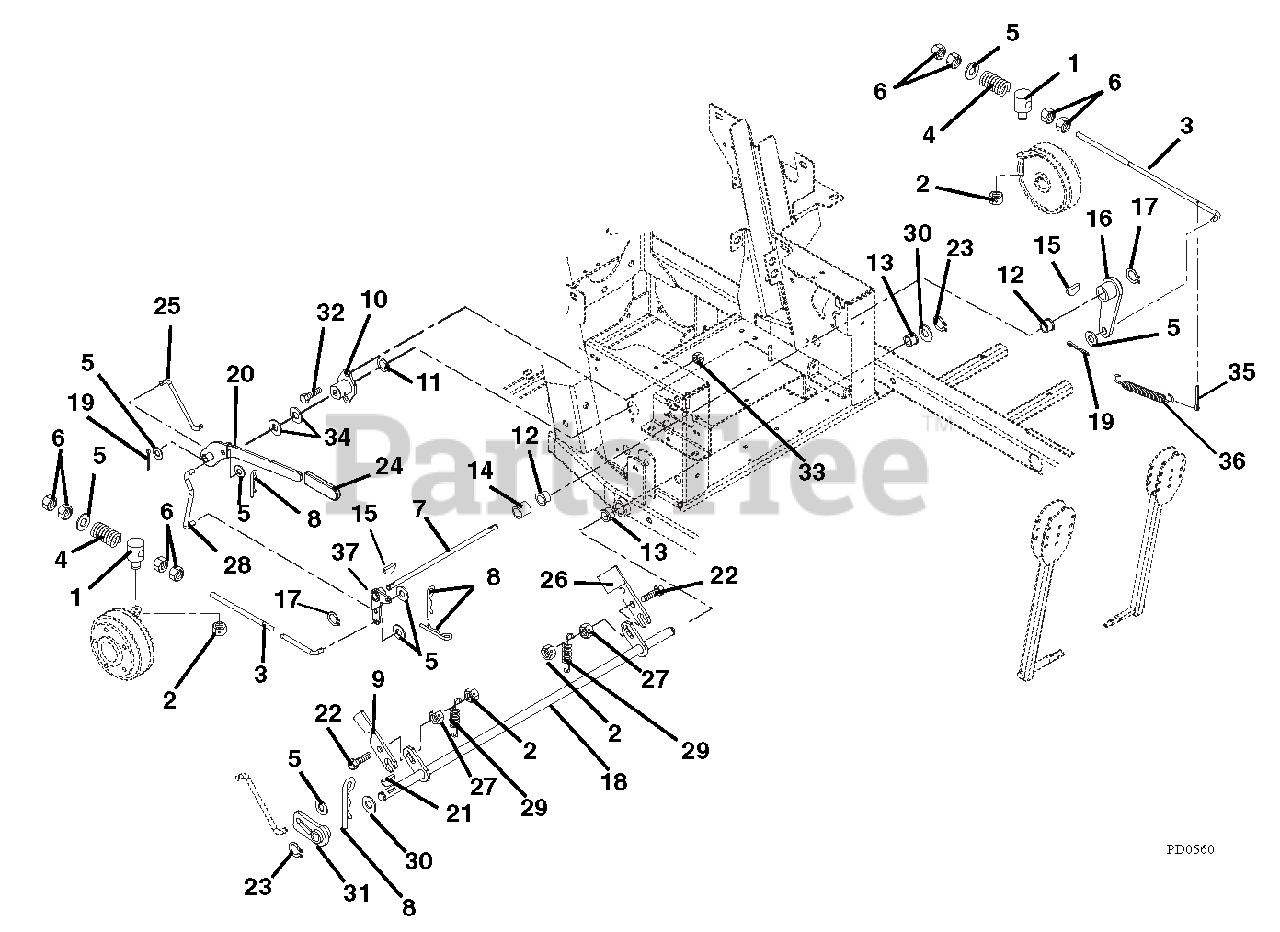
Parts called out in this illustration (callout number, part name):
1	PIN, PIVOT/TRUNNION
2	@NUT-LK-CTR .31-18 YWZC
3	PTO LINK ROD, PRO-150
4	SG-COMP .142 X .710 X 1.75
5	@WSHR-FL-STL.406X.812X.065 YWZ
6	@NUT-HEX .38-16 YWZC
7	SHAFT, 200 BRAKE
8	PIN-HAIR, ENDRIES #25 YWZC
9	SLIDE, INTERLOCKING BRAKE
10	BUSHING, FLANGED
11	RG-RTNG-EXT .625X.050
12	BSHG-FLG .762X1.0X.580X1.48 NY
13	BSHG-FLG .515X.750X.745X1.00NY
14	BSHG-SLV .750X1.000X.750
15	KEY-SQ .188X1.0X.188 SAE 8630
16	WMT, BRAKE ARM
17	RG-RTNG-EXT .689X.078
18	WMT, MECHANICAL BRAKE
19	@PIN-CTR .09X.75 EXTPRSQCT YWZ
20	WMT, BRAKE HANDLE
21	KEY-WDRF .13X.63 HRD#5
22	@BLT-RDHDSQNK .31-18X1.25 G5YZ
23	RG-RTNG-EXT .500X.050 (SNAP)
24	GRIP,HANDLE
25	LINKAGE, BRAKE ACTUATING
26	INTERLOCK, SAFETY SWITCH
27	@NUT-LK-TOP-FLG .31-18 YWZC
28	LINKAGE, BRAKE ACTUATING
29	SG-TENS .063X.44X1.56
30	WSHR-FL-STL .505X1.00X.062YWZC
31	WMT, PARKING BRAKE HUB
32	@BLT-HEX .31-18X.75 GR5 YWZC
33	@NUT-LK-TOP-FLG .31-18 YWZC
34	WSHR-FL-STL .630X1.250X.062 YZ
35	@PIN-CTR .12X.75 EXTPRSQCT YWZ
36	SPRING, EXT
37	WMT, 200 BRAKE ACT. ARM
